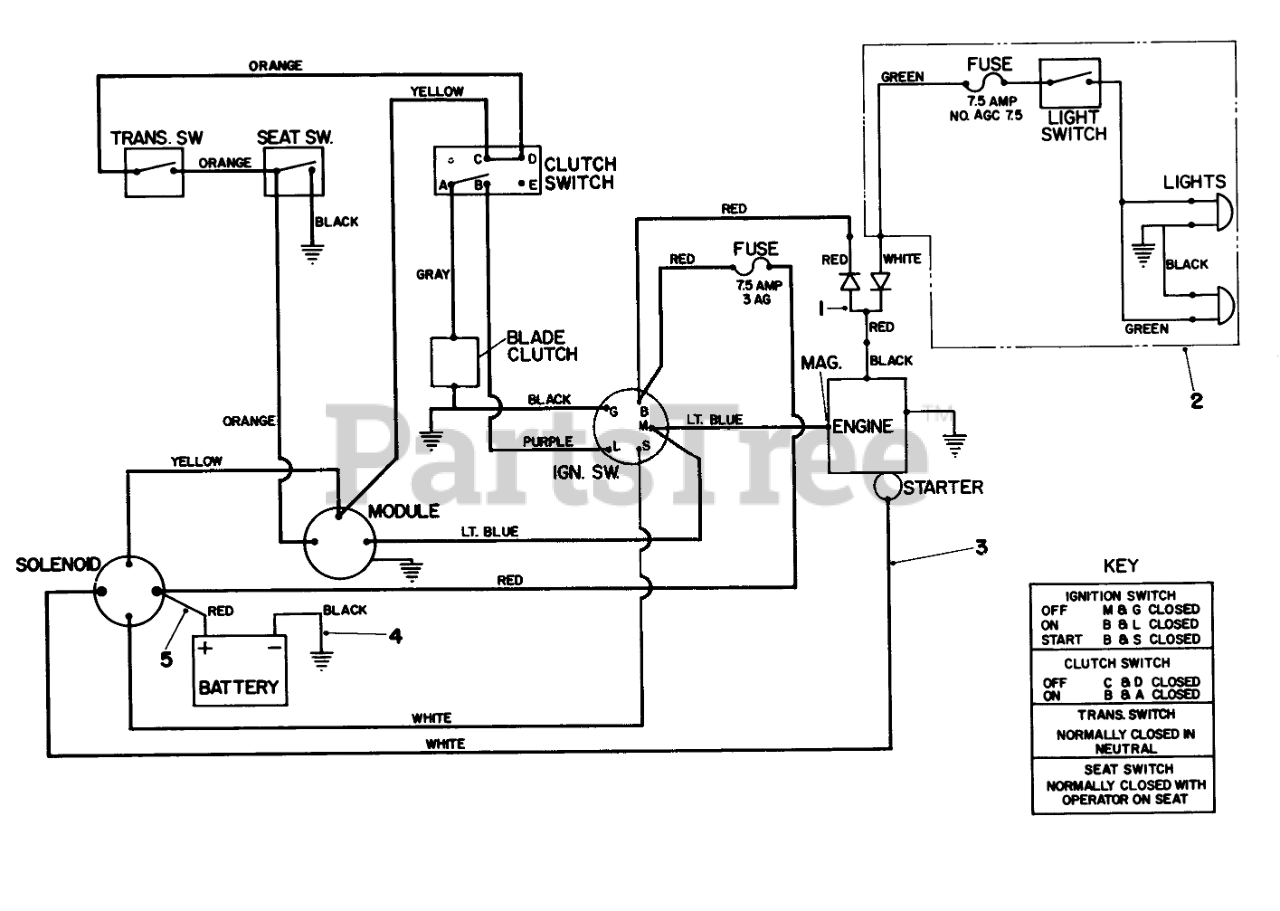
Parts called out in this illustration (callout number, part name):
1	WIRE HARNESS WIRE
2	WIRE HARNESS
3	WIRE HARNESS
4	WIRE ASM
5	WIRE ASM
